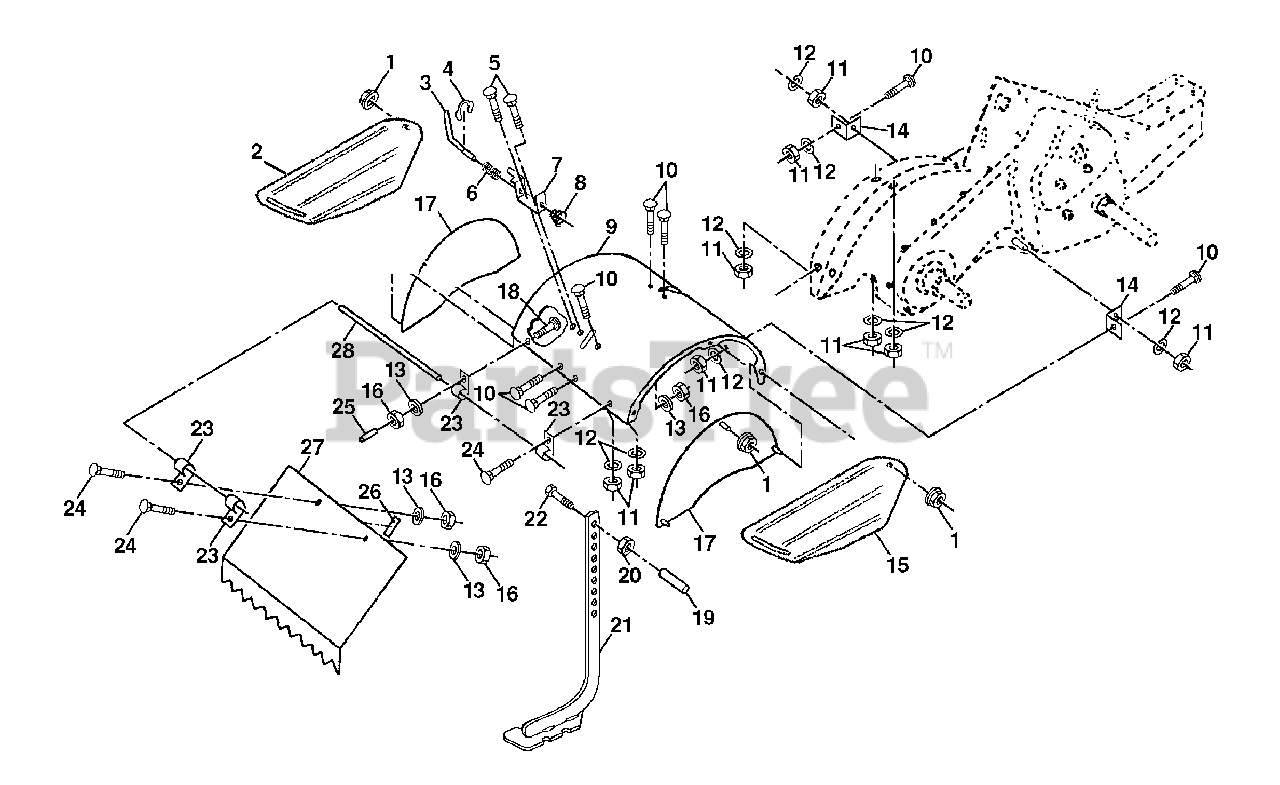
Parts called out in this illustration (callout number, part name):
1	Nut, Flange 5/16-18
2	Shield, Side, Outer, L.H.
3	Pin, Depth Stake
4	Ring, Klip
5	Bolt, Carriage 5/16-18 x 1
7	Bracket, Latch
8	Spring, Depth Stake
9	Shield, Tine
10	Bolt, Carriage 5/16-18 x 3/4 Gr. 5
11	Nut, Hex 5/16-18
12	Washer, Lock 5/16
13	Washer, Lock 1/4
14	Bracket, Shield Tine
15	Shield, Side, Outer R.H.
16	Nut, Fin, Hex, 1/4-20
17	Shield, Side
18	Bolt, Carriage 1/4-20 x 1-1/4 Gr. 5
20	Nut, Hex 3/8-16
21	Stake, Depth
22	Bolt, Hex 3/8-16 x 2
24	Bolt, Carriage 1/4-20 x 1/2 Gr. 5
25	Cap, Vinyl
26	Pad, Idler
27	Shield, Leveling
28	Pin, Hinge
